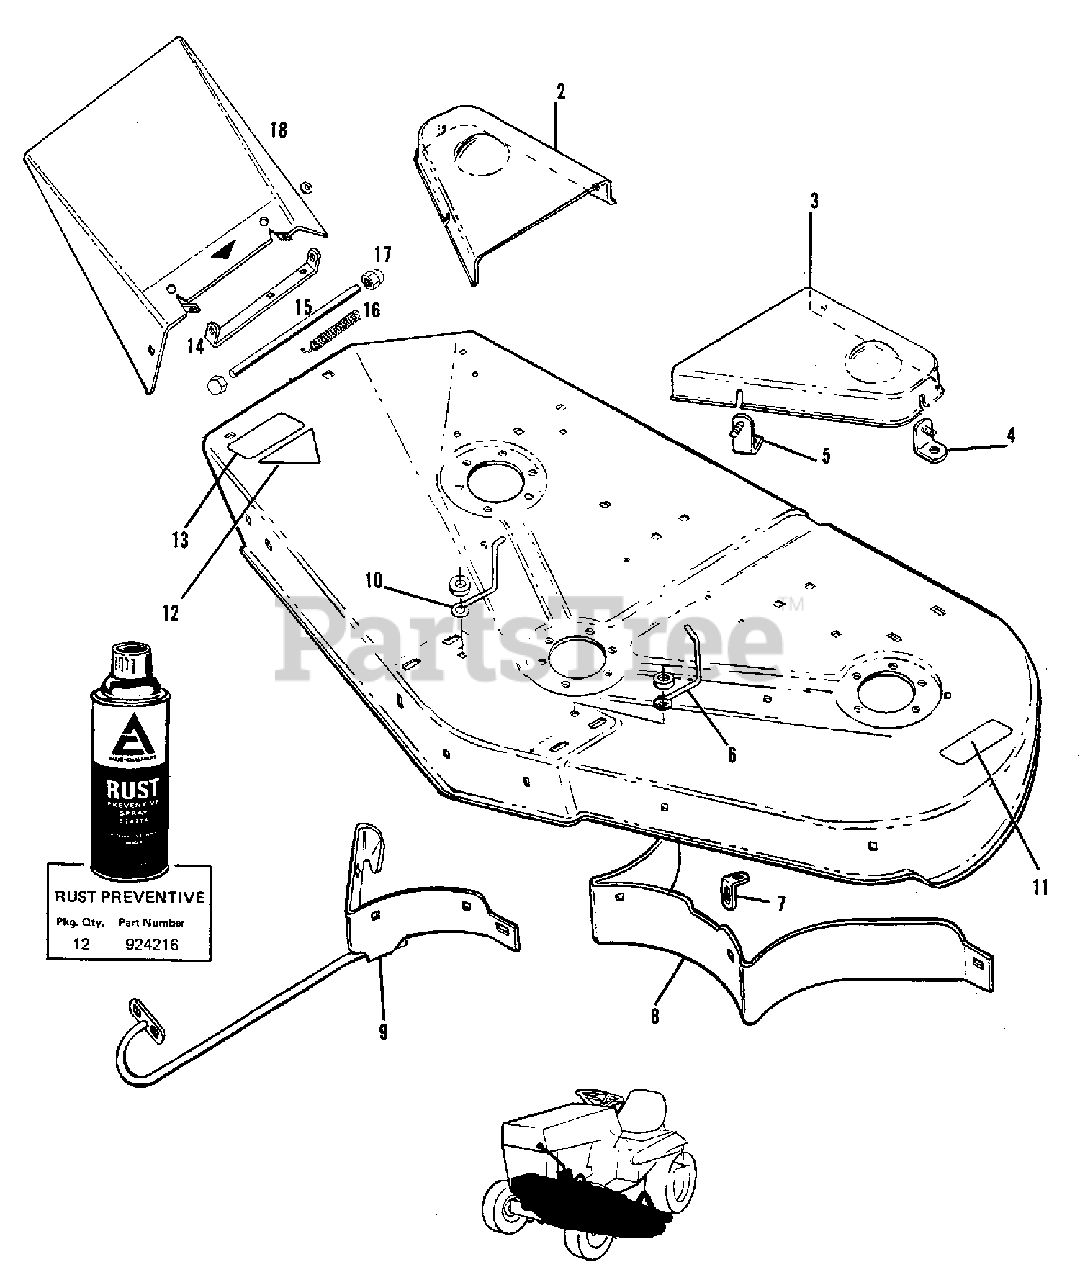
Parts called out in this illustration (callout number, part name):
1	HOUSING, Main, (42" Mower)
1	HOUSING, Main, (48" Mower)
2	COVER, Arbor, R.H.
3	COVER, Arbor, L.H.
4	LEG ASSEMBLY, Cover, Outer
4	BOLT, Carriage, 5/16NC x 3/4
4	WASHER, Plain, 5/16NC x 3/4
4	LOCKWASHER, 5/16
4	NUT, 5/16NC
4	LOCKWASHER, 1/4
4	NUT, 1/4NC
4	WASHER, Plain, 9/32 x 5/8 x 1/16 Thickness
5	LEG ASSEMBLY, Cover, Inner
5	BOLT, Carriage, 5/16NC x 3/4
5	WASHER, Plain, 3/8 x 7/8 x #16
5	LOCKWASHER, 5/16
5	NUT, 5/16NC
5	LOCKWASHER, 1/4
5	NUT, 1/4NC
5	WASHER, Plain, 9/32 x 5/8 x 1/16 Thickness
6	GUIDE, Belt, L.H.
6	BOLT, Carriage, 5/16NC x 3/4
6	WASHER, Plain, 3/8 x 7/8 x #16
6	LOCKWASHER, 5/16
6	NUT, 5/16NC
7	CLIP, Baffle (42" Mower)
7	CLIP, Baffle (48" Mower)
7	BOLT, Carriage, 1/4NC x 5/8
7	CAPSCREW, 1/4NC x 3/4
7	WASHER, .344 x 1 x 10 Ga.
7	WASHER, Plain, 5/16 x 3/4 x #16
7	LOCKWASHER, 1/4
7	NUT, 1/4NC
8	BAFFLE, Housing (42" Mower)
8	BAFFLE, Housing (48" Mower)
8	BOLT, Carriage, 3/8NC x 3/4
8	LOCKWASHER, 3/8
8	NUT, 3/8NC
9	GUARD ASSEMBLY, Discharge (42" Mower)
9	GUARD ASSEMBLY, Discharge (48" Mower)
9	BOLT, Carriage, 5/16NC x 1
9	BOLT, Carriage, 3/8NC x 3/4
9	LOCKWASHER, 5/16
9	LOCKWASHER, 3/8
9	NUT, 5/16NC
9	NUT, 3/8NC
10	GUIDE, Belt, R.H.
10	BOLT, Carriage, 5/16NC x 3/4
10	WASHER, Plain, 3/8 x 7/8 x #16
10	LOCKWASHER, 5/16
10	NUT, 5/16NC
11	TRANSFER (Caution)
12	DECAL, Danger
13	DECAL, Safety
14	HINGE, Support (Eff. S/N 41101 & Up)
14	BOLT, Carriage, 5/16NC x 5/8 (Eff. S/N 41101 & Up)
14	LOCKWASHER, 5/16 (Eff. S/N 41101 & Up)
14	NUT, 5/16NC (Eff. S/N 41101 & Up)
15	PIN, Hinge (Eff. S/N 41101 & Up)
16	HINGE, Spring (Eff. S/N 41101 & Up)
17	FASTENER, Pushnut (Eff. S/N 41101 & Up)
18	DEFLECTOR (Eff. S/N 41101 & Up)
18	BOLT, Carriage, 3/8NC x 3/4 (Eff. S/N 41101 & Up)
18	WASHER, 13/32 x 1-1/2 (Eff. S/N 41101 & Up)
18	LOCKWASHER, 3/8 (Eff. S/N 41101 & Up)
18	NUT, 3/8NC (Eff. S/N 41101 & Up)
